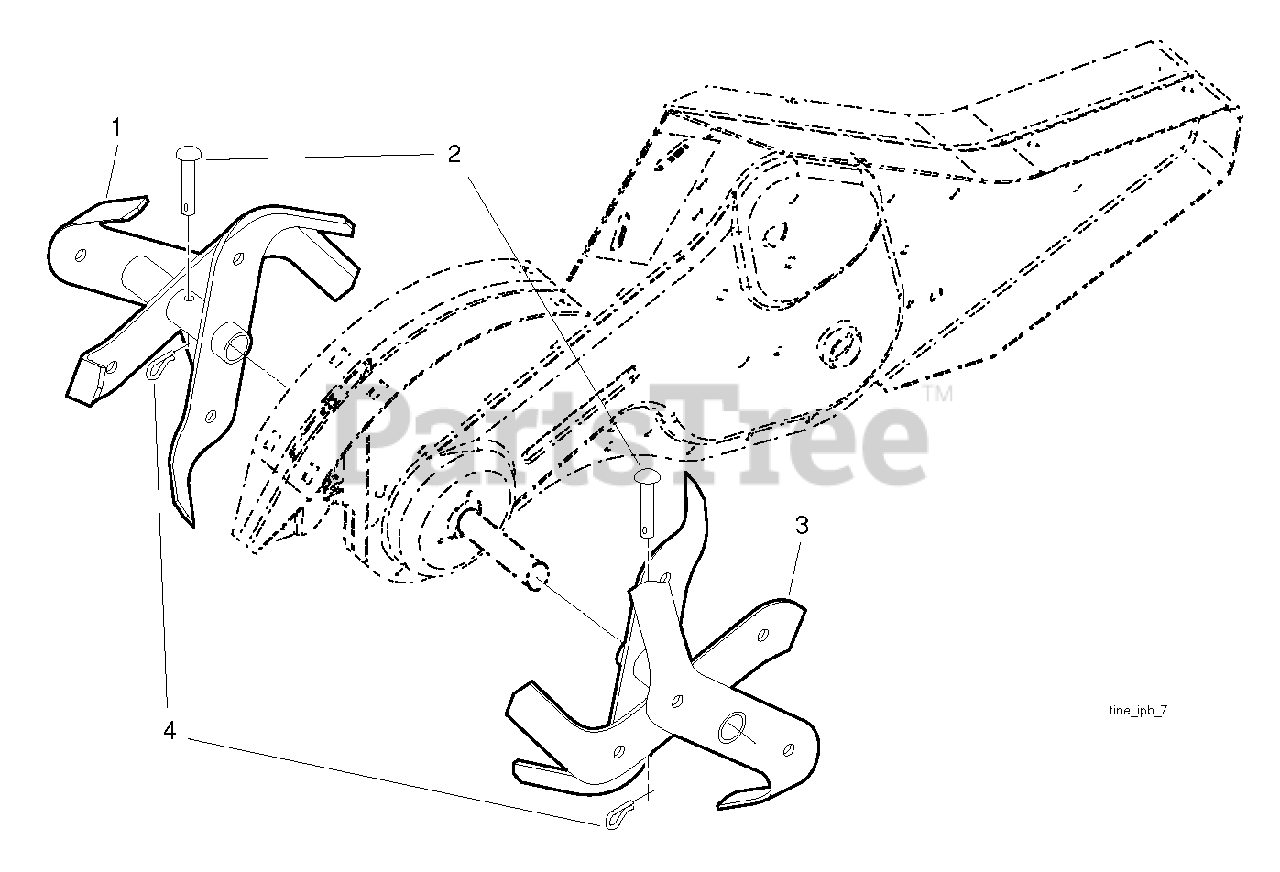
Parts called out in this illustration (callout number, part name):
1	TINE.ASM.LH.TILLER.BLACK
2	CLEVIS PIN
3	TINE.ASM.RH.PNT.479
4	SPRING RETAINER
